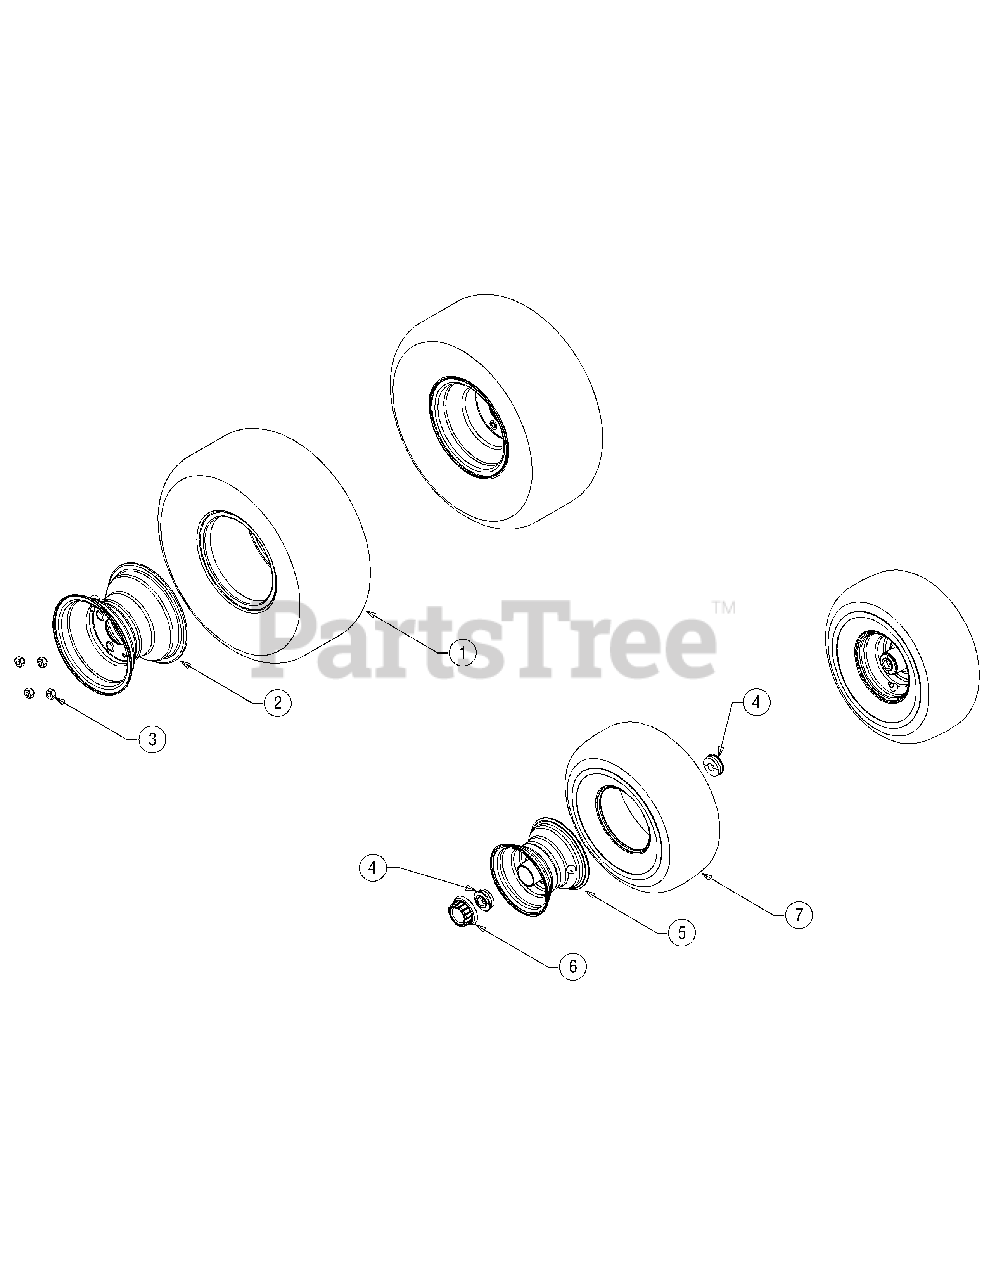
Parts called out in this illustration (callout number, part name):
1	Wheel Ass’y, Complete, 22 x 9.5 x 12
1	Tire, Turf, 22 x 9.5 x 12
2	Rim Assembly,
3	Lug Nut, 7/16-14
4	Bearing, Ball, .75 ID x 1.75 OD
6	Hub Cap
7	Tire, Turf, 15 x 6 x 6
7	Wheel Ass’y, Complete, 15 x 6 x 6
